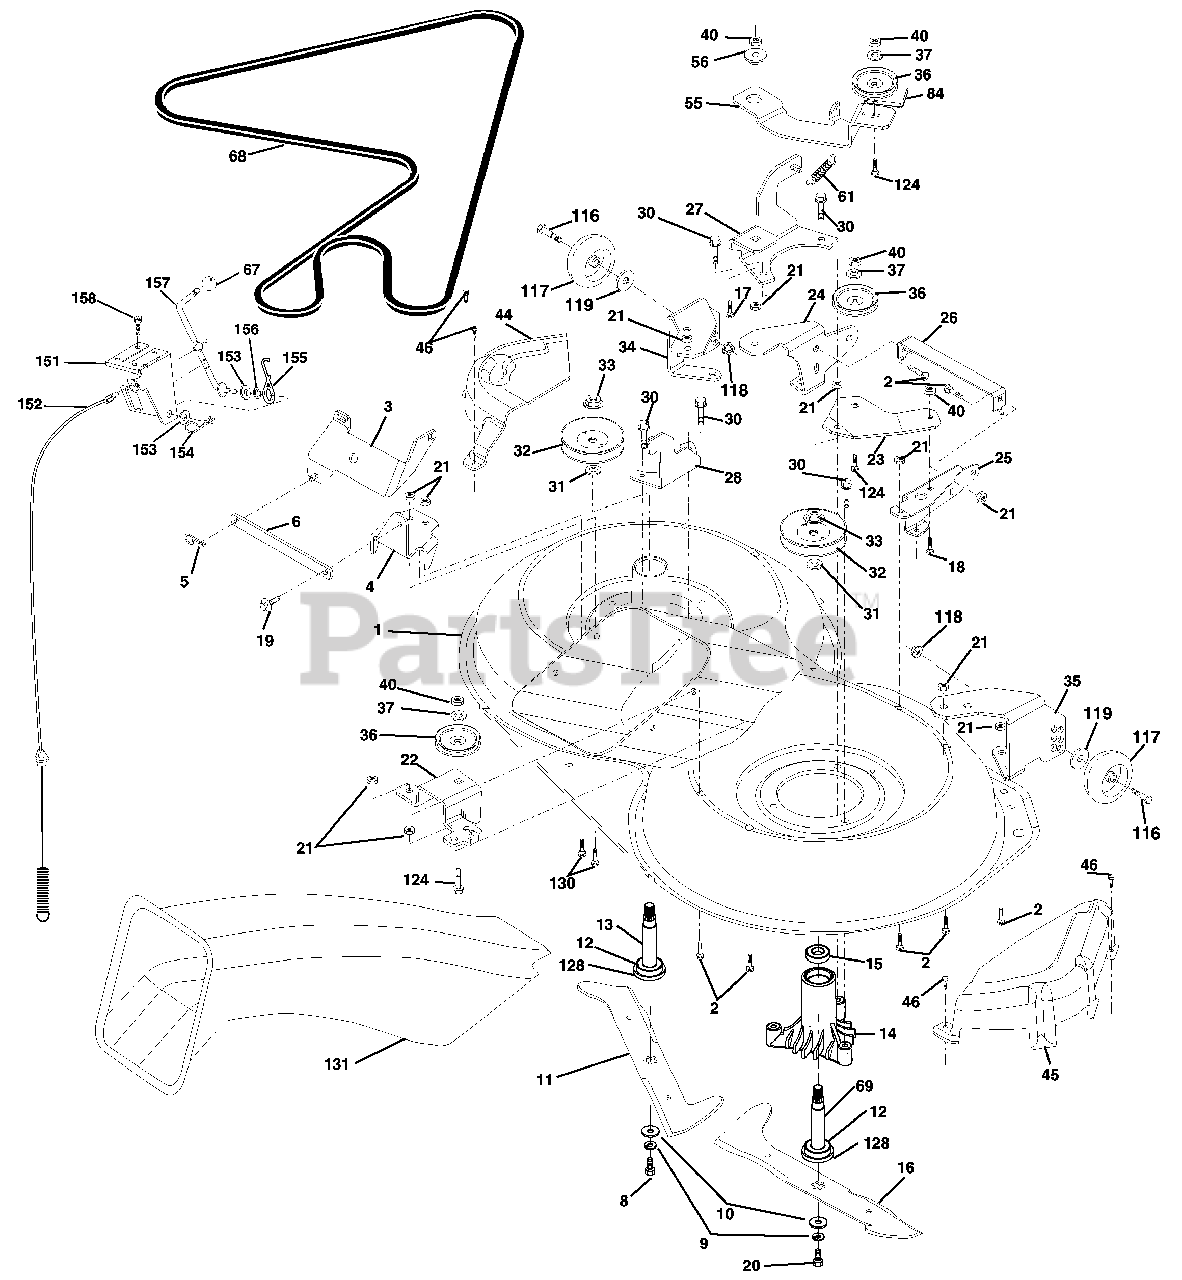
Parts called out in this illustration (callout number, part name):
1	Housing Asm. Mower 92 CRD
2	Bolt Rdhd Sqnk 5/16-18 Unc x 3/4
3	Bracket Asm. S-Bar Chass 92 CRD
4	Bracket Bar Sway Deck 92 CRD
5	Retainer Spring
6	Bar Sway 92 CRD
8	Bolt 3/8-24 x 1.25 Gr8 Patched
9	Washer Lock Hvy 3/8 Unplated
10	Washer Hard Blade Mower vented
11	Blade 3-1 Lh 92 CRD
12	Bearing Ball #6204 (Mandrel)
13	Shaft Asm. W/Lower Bearing
14	Housing Mandrel Vented (Machd)
15	Bearing Ball Mandrel
16	Blade 3-1 Rh 92 CRD
17	Bolt Carriage 3/8-16 x 1-1/4
18	Bolt Rdhd Sqnk 3/8-16 x 1 Gr5
19	Bolt Shoulder 5/16-18 Thd Form
20	Bolt 3/8-24 x 1.25 Gr8 Ptch Lhthd
21	Nut Crown Lock 5/16-18
22	Bracket Idler Sprt RR 92 CRD
23	Bracket Idler Sprt RF 92 CRD
24	Bracket Suspension LF 92 CRD
25	Bracket Suspension RF 92 CRD
26	Brace Support Susp Frt CRD
27	Bracket Asm. Susp RR 92 CRD
28	Bracket Asm. Susp LR 92 CRD
30	Screw Thd Rolling Washer Head
31	Washer Spacer Mower Vented
32	Mandrel Pulleys 36 & 46
33	Nut Flg Top Lock Cntr B 9/16
34	Bracket Gauge Wheel Lf 92 CRD
35	Bracket Gauge Wheel Rf 92 CRD
36	Pulley Idler V-Groove Dim 4.25
37	Washer 11/32 x 13/16 x 16 Ga
40	Nut Crownlock 3/8-16 Unc
44	Cover Mandrel Lh 92 CRD
45	Cover Mandrel Rh 92 CRD
46	Screw Thd Roll 1/4-20 x 5/8
55	Arm Idler 92 CRD
56	Spacer Retainer Mower
61	Spring Tension Belt
67	Knob Rd 3/8-16 Plstc Thds Blk
68	Hex-Belt 92 Mower 105AA
69	Shaft Asm W/Lwr Brg Rh Thd CRD
84	Keeper Belt Idler
116	Bolt Shoulder
117	Wheel Gage Donut Wide
118	Nut Centerlock 3/8-16 Unc
119	Washer 3/8 x 7/8 x 14 Ga.
124	Bolt Carr Sh 3/8-16 x 1-1/2 Gr5
128	Washer Felt
130	Bolt Rdhdsqnk 5/16-18 Unc x 3/4
131	Chute Bagger CRD 92cm
151	Bracket Clutch Cable
152	Cable Clutch CRD
153	Washer Flat 3/8" Type B
154	Spring Retainer
155	Spring Retention
156	Spacer Clutch Cable
157	Rod Clutch Cable 3/8"
158	Screw Hex Thd Cut 1/4-20 x 5/8
